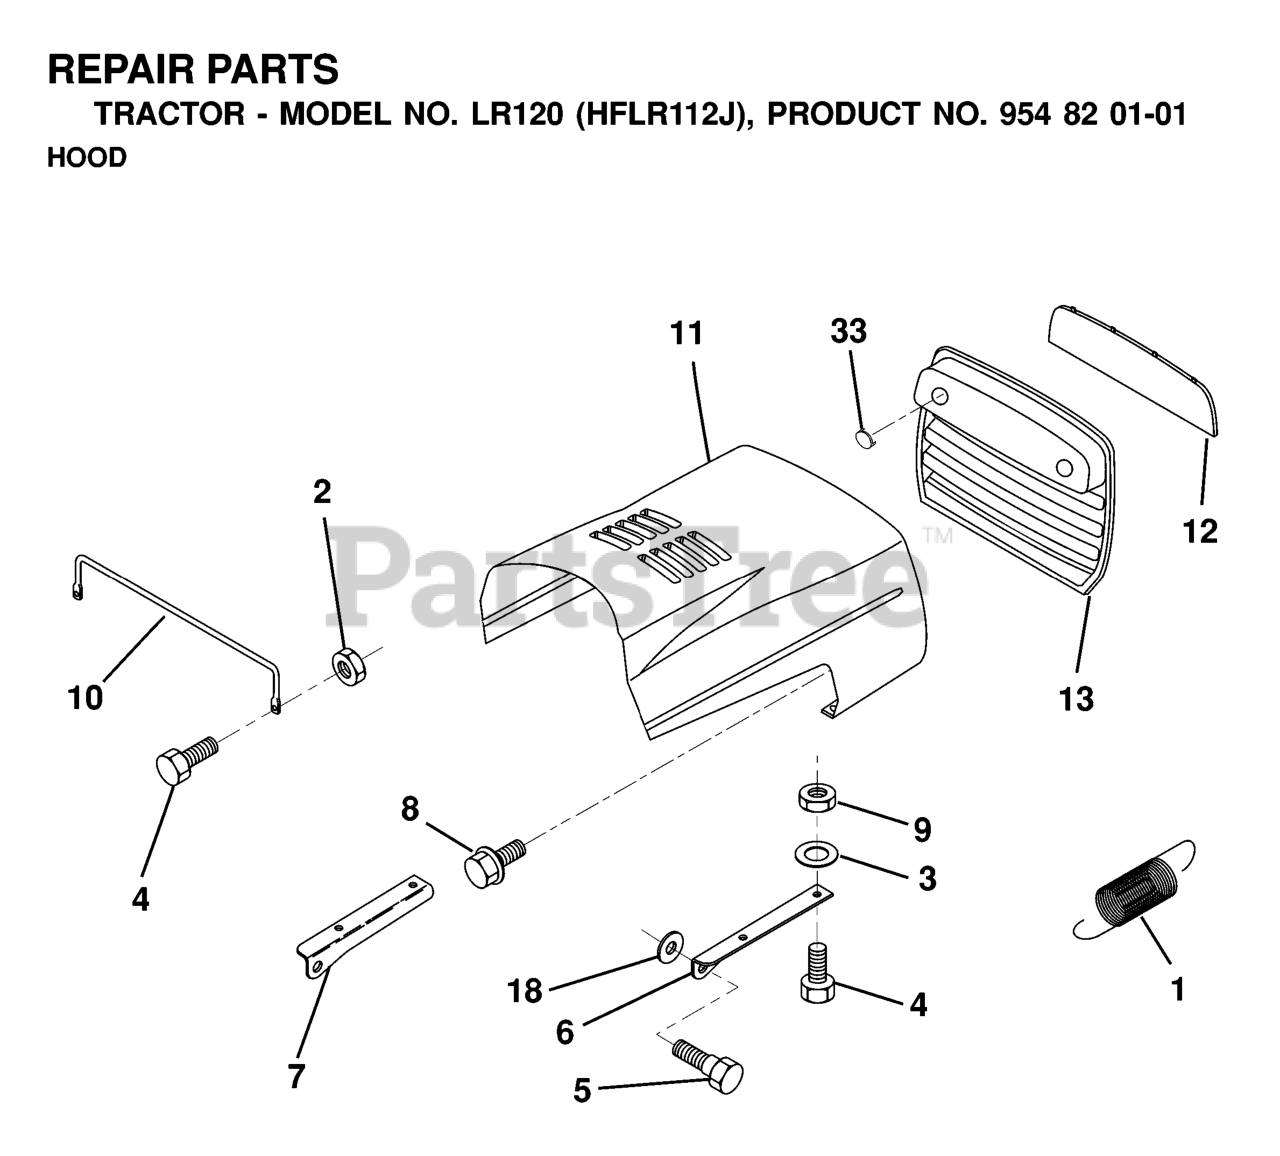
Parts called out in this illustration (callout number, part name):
1	EXT SPRING
2	NUT
4	BOLT
5	BOLT.SHOULDER.5/16-18
6	BRKT HOOD RH
7	BRKT HOOD LH
8	SCREW
9	LOCKNUT.NYLOC.1/4-20
10	BRACE,HOOD
11	HOOD
13	GRILL YP W/HL
18	WASHER
33	CVR LIGHT SOCKET
